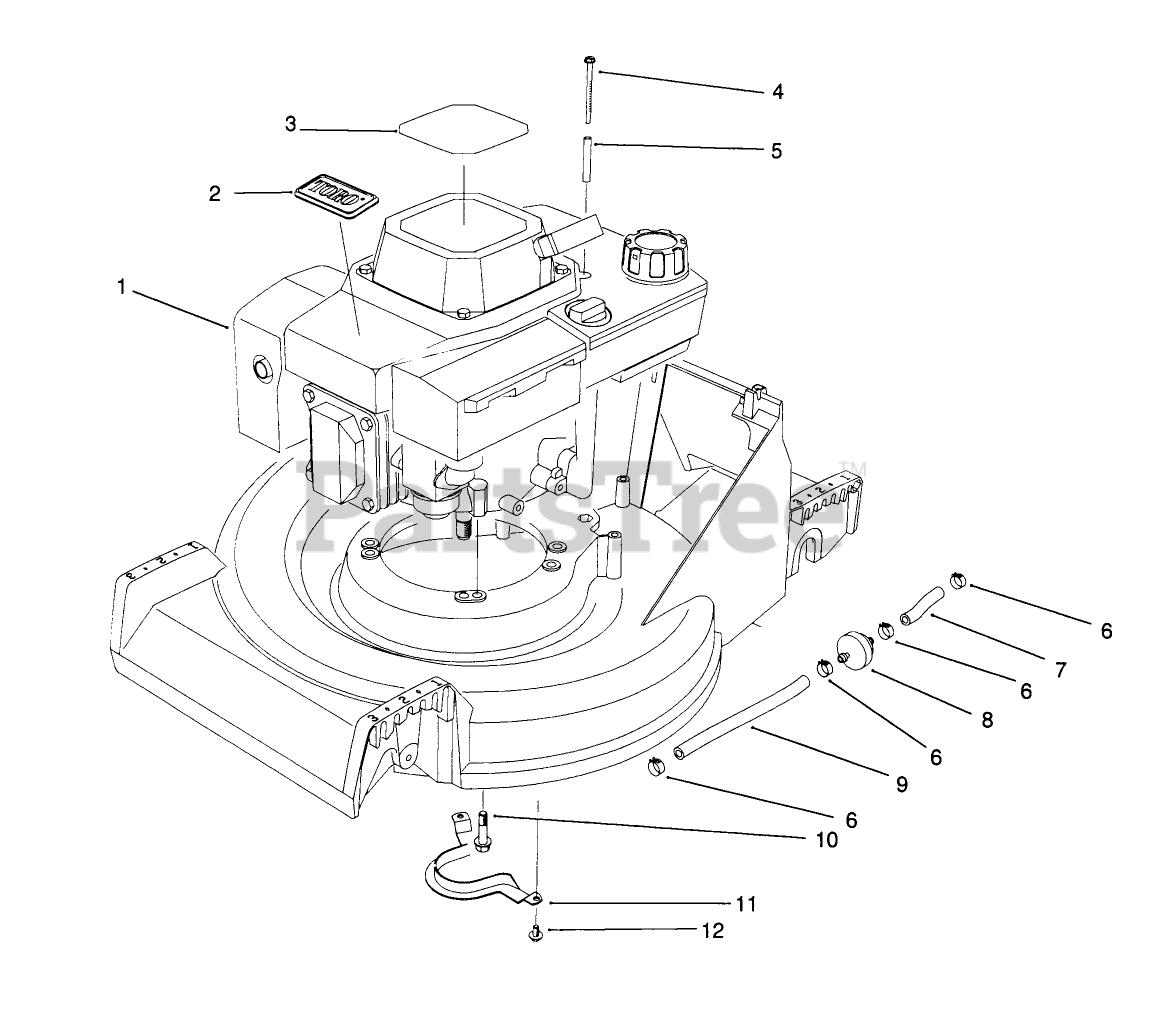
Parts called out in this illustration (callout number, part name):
4	THRD FORMING SCREW
5	TUBULAR SPACER
6	CLAMP-FUEL LINE
7	HOSE-FUEL
8	FILTER-FUEL
9	HOSE-FUEL
12	SCREW-HWHTF
